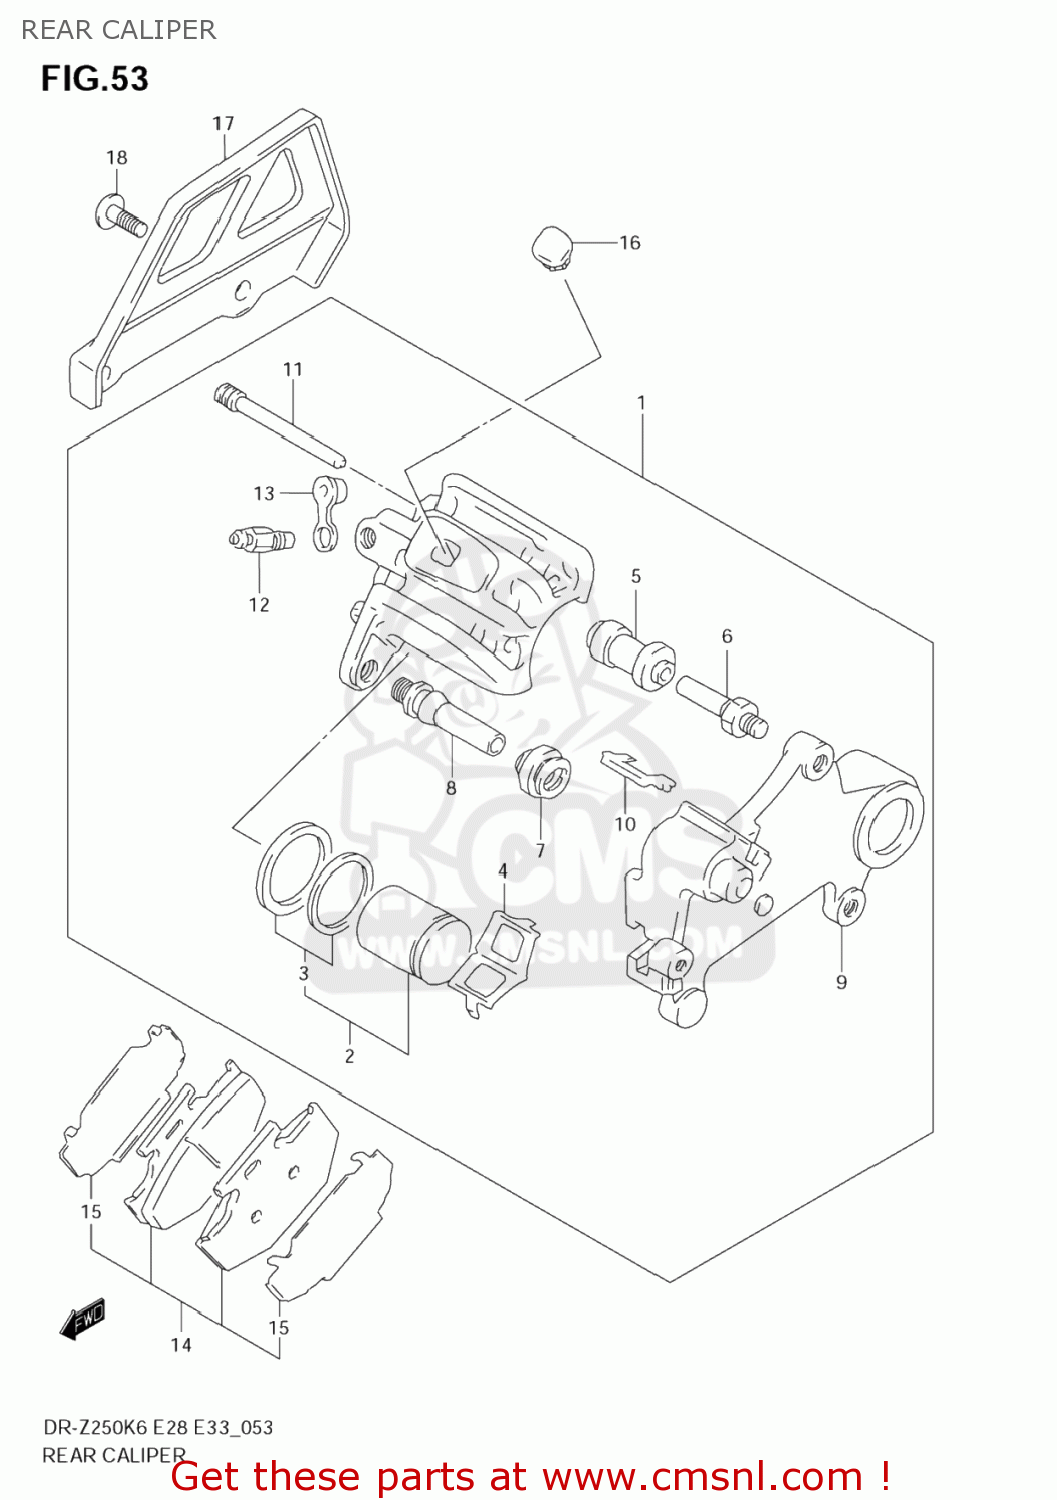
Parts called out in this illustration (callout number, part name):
1	CALIPER ASSY,RR
2	PISTON SET
3	SEAL SET,PISTON
4	SPRING,PAD
5	BOOT
6	BOLT
7	BOOT
8	PIN
9	BRACKET
10	RETAINER,BRACKET
11	PIN,HANGER
12	BLEEDER
13	CAP,BLEEDER
14	PAD & SHIM SET (NAS)
15	SHIM
16	COVER,RR CALIPER BODY
17	GUARD SET,REAR CALIPER
18	SCREW 6X12
